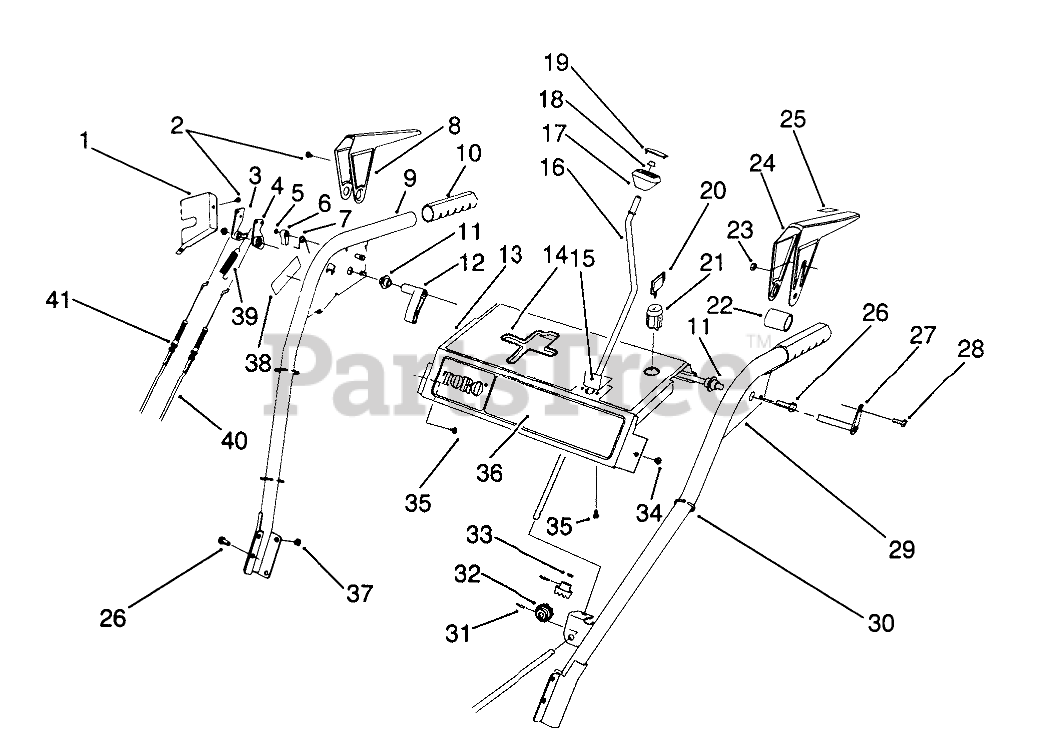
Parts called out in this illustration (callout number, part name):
1	Cover Lever Lock
2	SCREW-HH
3	TANG-LOCKING
4	CAM-RELEASE
5	E-RING-RETAINER
6	LATCH-LOCKING
7	SPRING-TORSION
8	Lever-Impeller
9	Handle-R.H.
10	GRIP-HANDLE
11	BUSHING-LEVER
12	LEVER-TRIP
13	Panel-Control
14	DECAL-TOP PANEL
15	PLATE-GUIDE
16	CRANK-ROD, CHUTE
17	KNOB-CONTROL, CHUTE
18	RETAINER-PUSH ON
19	COVER-KNOB
20	KEY-IGNITION
21	SWITCH
22	SPACER-LEVER, TRACTION
23	NUT-LOCK, NI
24	Lever-Traction
25	DECAL-LEVER
26	SCREW-HHF
27	CROSS ROD ASM
28	SCREW-HWH
29	Handle-L.H.
30	TIE-CABLE
31	PIN-SPRING
32	GEAR-UNIVERSAL
33	WASHER-RUBBER
34	SCREW-HWHTF
35	SCREW-PPH
36	DECAL-FRT PANEL (1132)
37	NUT-LOCK, NI
38	DECAL-WARNING
39	Spring-Extension
40	CABLE-TRACTION
41	CABLE-IMPELLER
